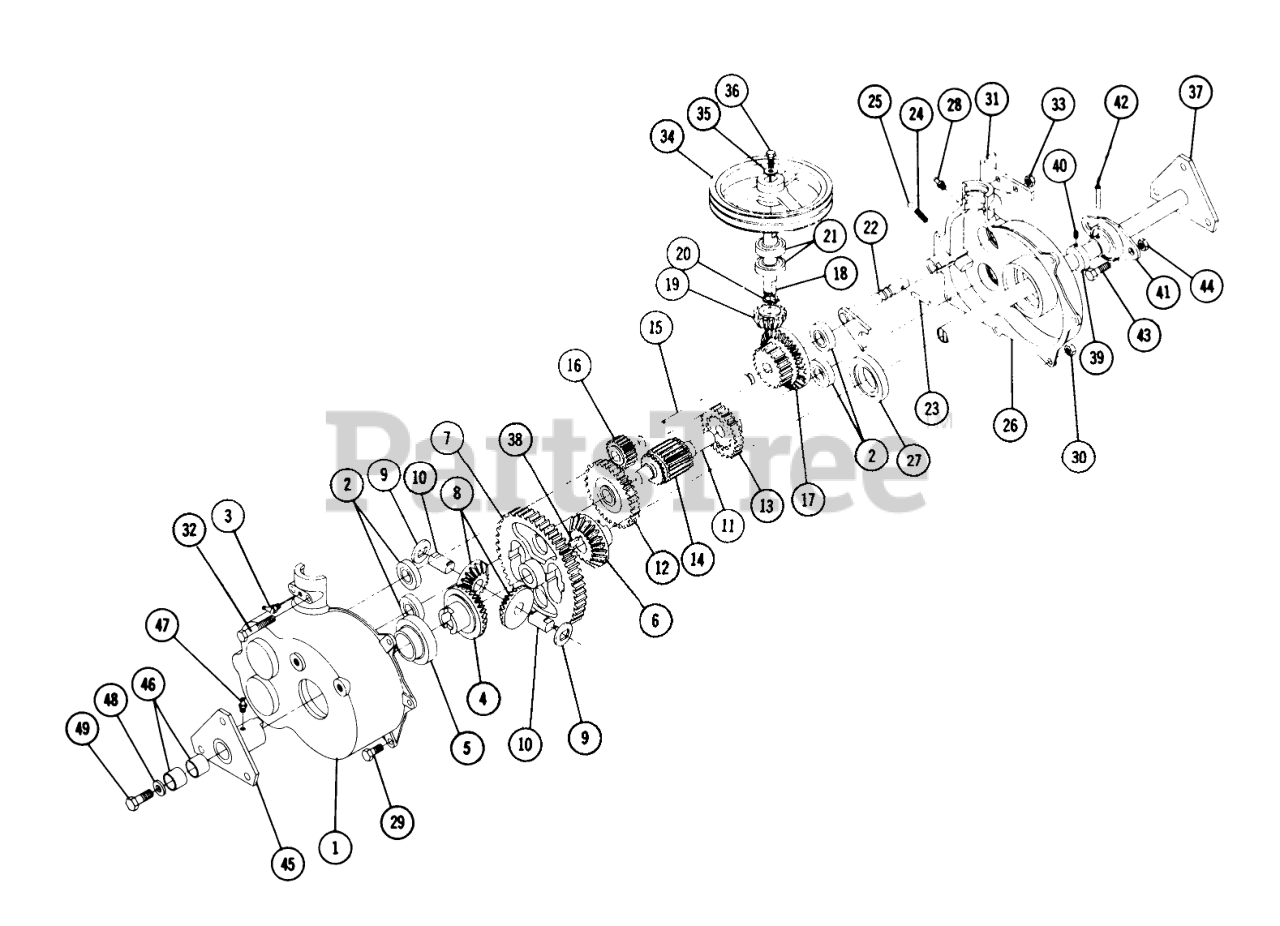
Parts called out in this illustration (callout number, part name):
3	FITTING-GREASE
20	SNAP RING- 5/8 EXT
23	PIN-SPIROL
25	BALL-DETENT
29	Bolt, 5/16-18 X 7/8
30	Nut 5/16-18 Keps
31	Bracket Shift Rod
32	Bolt Hex 5/6-18 X 2-1/2
33	Nut-Nylok
35	Washer
36	Bolt-Hex 5/16-18 x 5/8 Nylok
38	WOODRUFF KEY
40	Set Screw 1/4-20 x 1/4
42	Spirol Pin
43	Bolt Hex 3/8-16 x 5/8
46	BUSHING-BRONZE
47	Fitting
48	WASHER
49	Bolt 3/8-16 x 3/4 Hex
